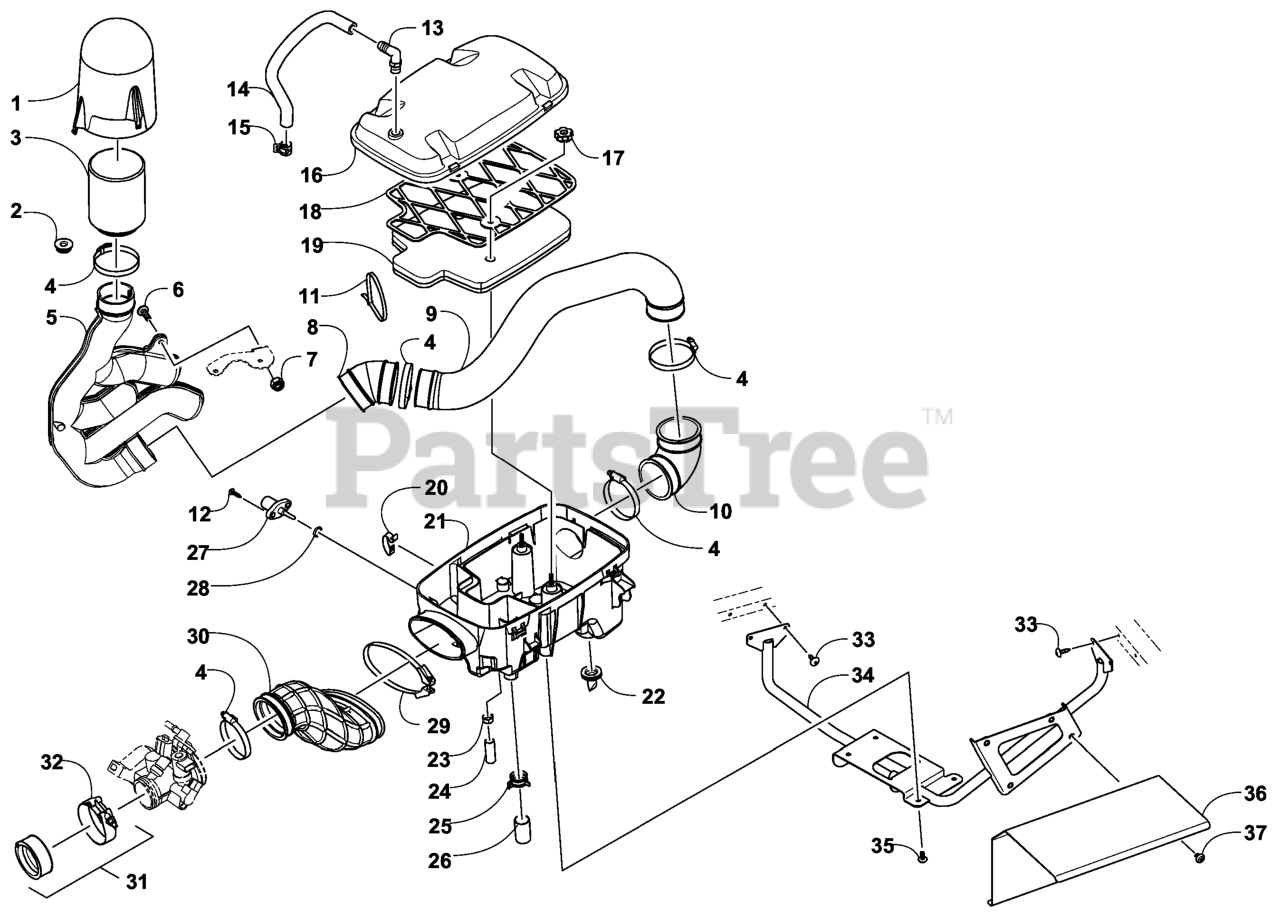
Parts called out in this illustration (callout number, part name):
1	SHIELD-DEBRIS, PRE-FILTER
2	GROMMET-PANEL, SIDE
3	FILTER-DUST
4	CLAMP-WORM, HOSE
5	DUCT-AIR IN
6	CHAIN,DRIVE
7	NUT-HHF, LOCK, (NI)
8	BOOT-AIR DUCT, 45 DEGREE
9	DUCT-INTAKE
10	BOOT-AIR DUCT
11	TIE-CABLE
12	SCREW-SELF TAPPING
13	Fitting, Elbow
14	HOSE-VENT
15	CLAMP-SPRING, HOSE
16	BOX-AIR,TOP
17	KNOB-ADJUSTMENT
18	SCREEN-AIR FILTER
19	FILTER-AIR BOX
20	CLIP-SPRING
21	BOTTOM-AIR BOX (WITH INSE
22	VALVE-AIR CLEANER
23	CLAMP-HOSE
24	CAP-DRAIN, AIRBOX
25	CLAMP-SPRING, HOSE
26	CA-DRAIN, AIR BOX
27	SENSOR-AIR TEMP
29	CLAMP-DUCT
30	RUNNER-INTAKE
31	KIT-SERVICE, INTAKE BOOT
32	CLAMP-MANIFOLD, T-BOLT
33	SCREW-TSTRH, SELFTAP
34	MOUNT-AIR BOX
35	LINKAGE,BRAKE
36	SHIELD-HEAT, AIRBOX
37	SPROCKET,GEARBOX 5 SPEED
